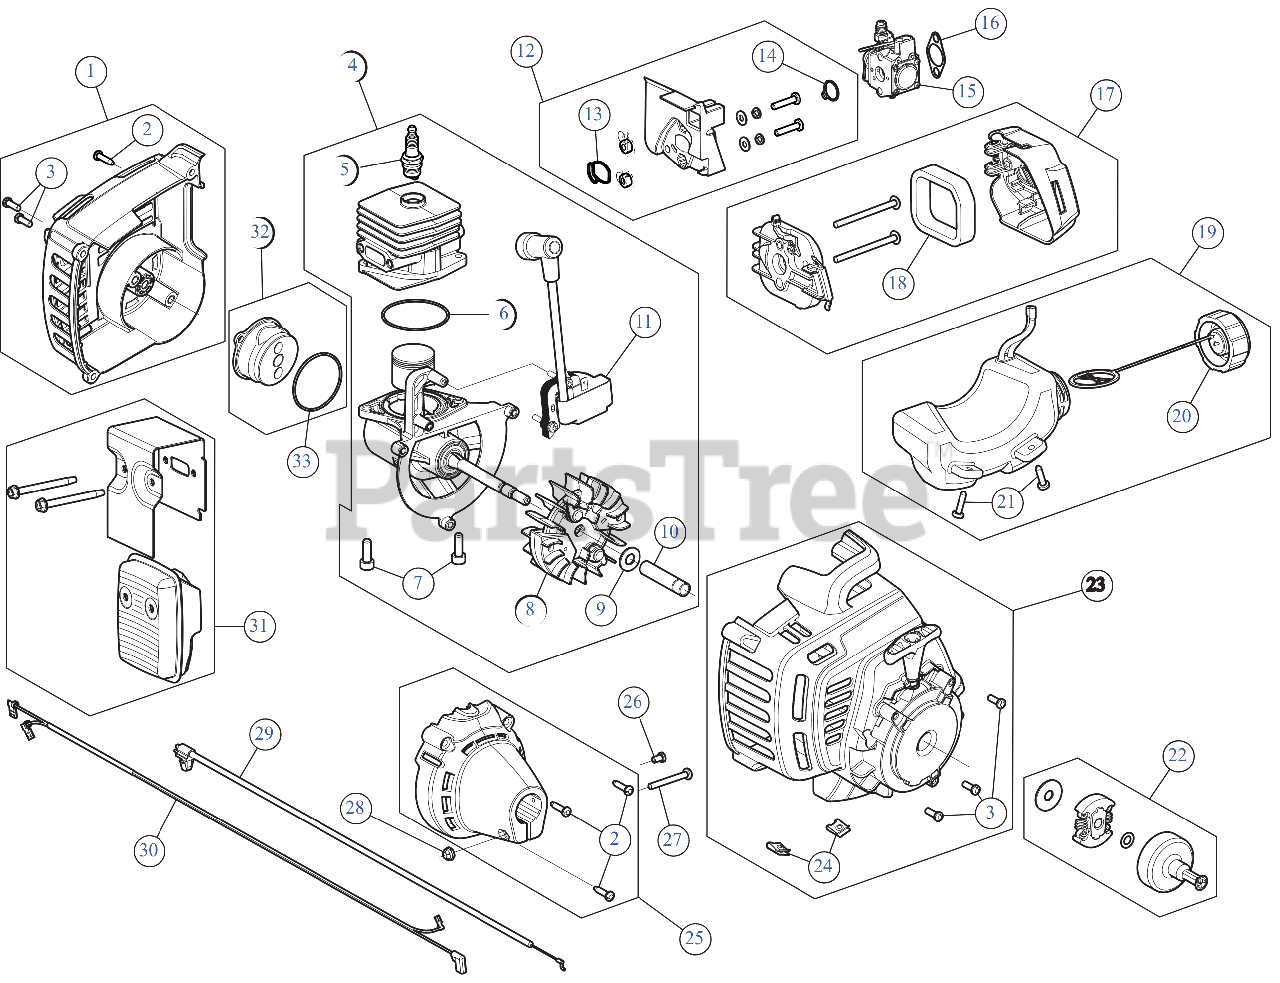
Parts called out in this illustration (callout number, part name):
1	REAR ENGINE COVER
2	SCREW, #8-16X.750 PH
3	SCREW:10-32X.562:#8P
4	SHORT BLOCK
5	SPARK PLUG
6	O-RING
7	SCREW, 1/4-20 x .75
8	FLYWHEEL ASSEMBLY
9	BELL WASHER
10	SPACER
11	MODULE 27CC DIG
12	INTAKE ASSEMBLY
13	O-RING
14	O-RING
15	CARBURETOR
16	GASKET CARB
17	AIR CLEANER ASSEMBLY
18	AIR FLITER
19	FUEL TANK ASSEMBLY
20	FUEL CAP ASSEMBLY
21	SCREW:10-6 x .75
22	SMALL CLUTCH ASSEMBLY W/SMALL DRUM
23	STARTER HOUSING ASSEMBLY
24	NUT, TINNERMAN U-T
25	CLUTCH COVER
26	SCREW, 8-32 x .312 P
27	SCREW
28	HEX NUT
29	THROTTLE CABLE
30	LEAD WIRES
31	MUFFLER ASSEMBLY
32	ELECTRIC START COVER
33	O-RING
